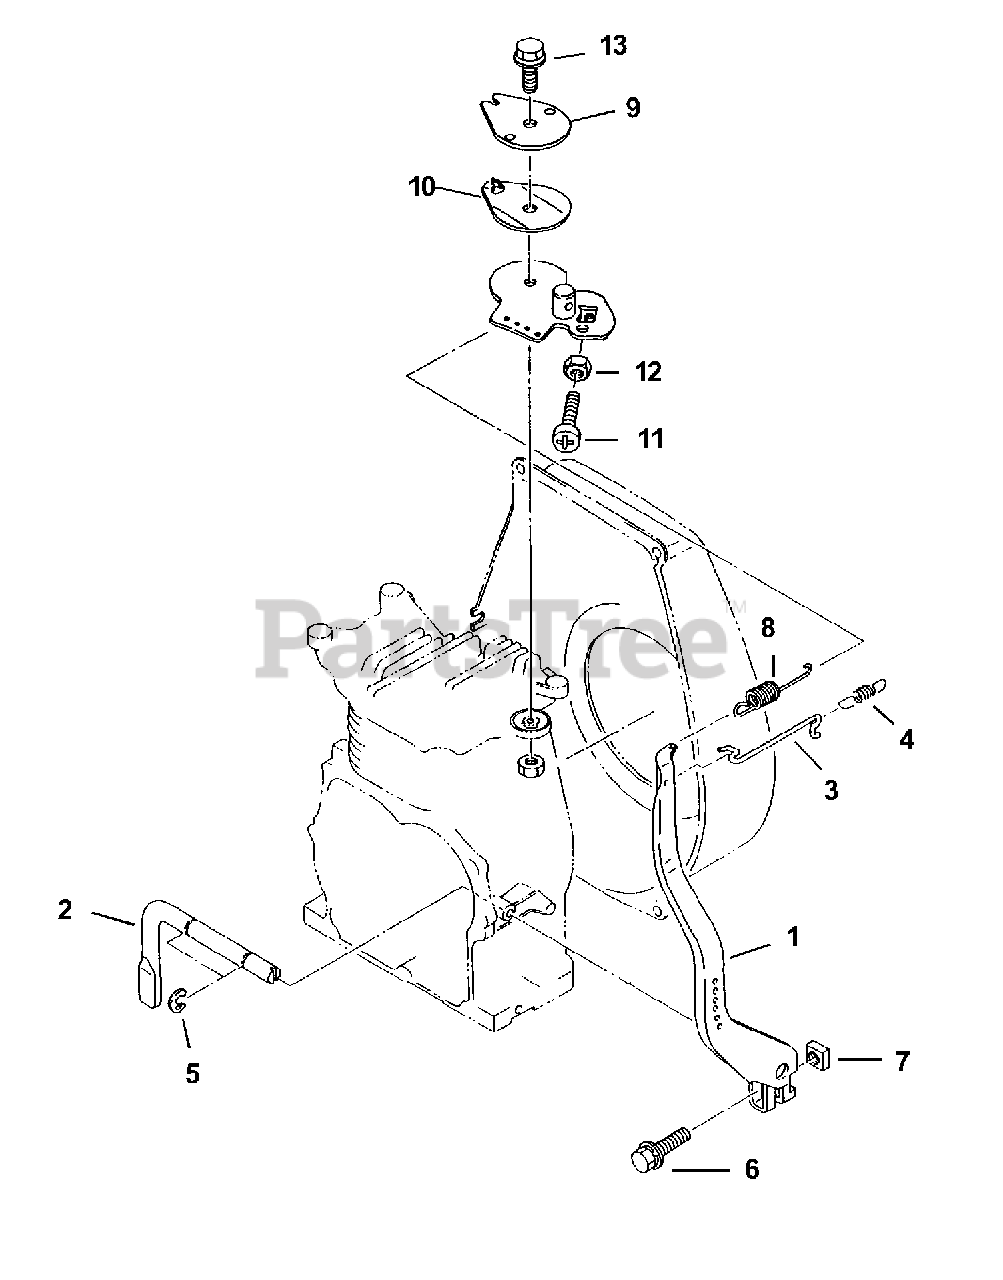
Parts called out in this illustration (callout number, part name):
1	Governor lever
2	Governor shaft
3	Governor rod
4	Rod spring
6	Bolt & washer (M6 X 1.0 X 25L)
7	Nut (M6 X 1.0)
8	Governor spring
9	Stop plate
10	Spring washer
12	Nut (M6 X 1.0)
13	Flange bolt (M6 X 1.0 X 14L)
